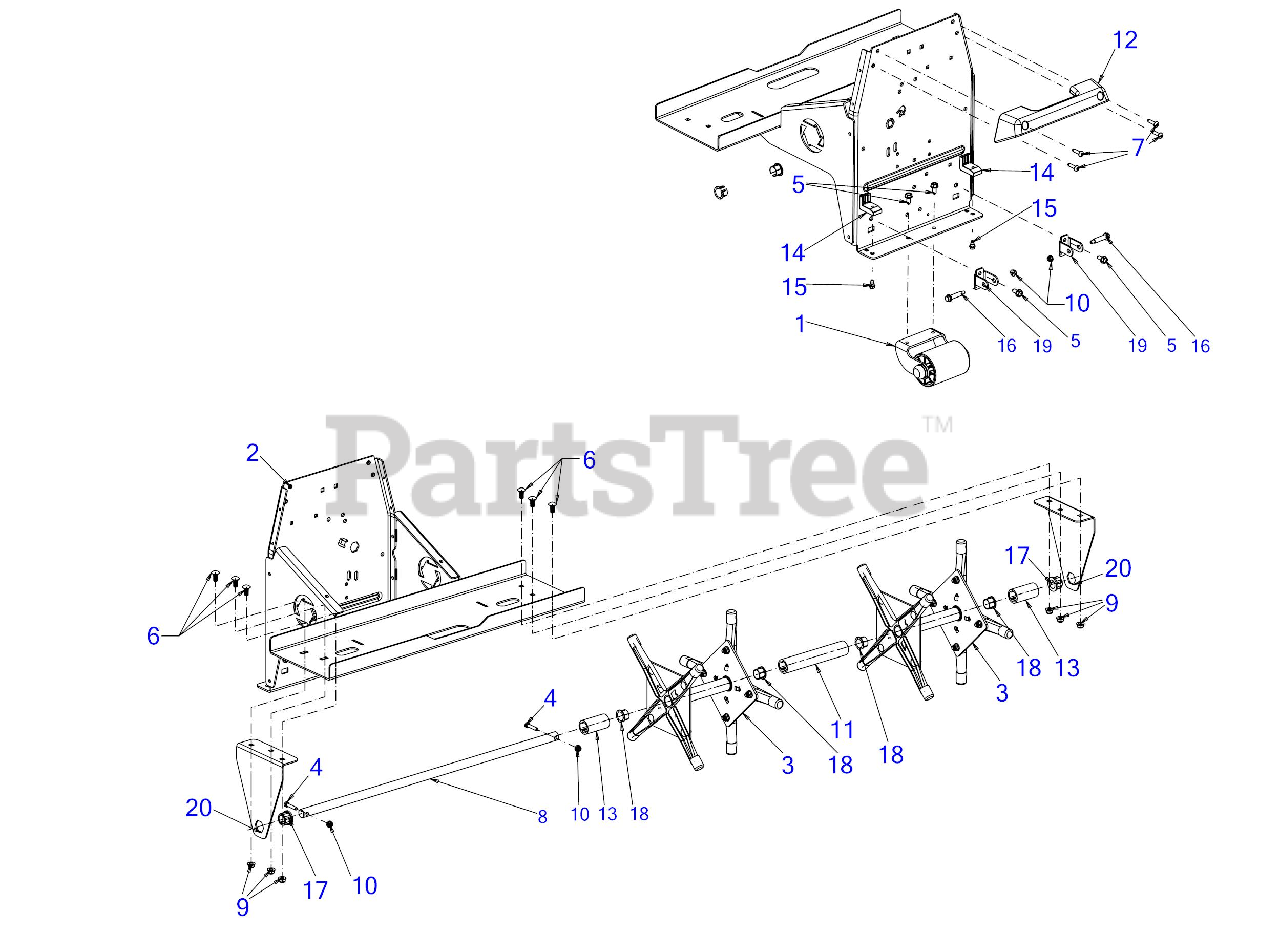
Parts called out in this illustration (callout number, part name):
1	ROLLER BRACKET ASSEMBLY
2	AERATOR FRAME ASSEMBLY
3	AERATOR DOUBLE WELD ASSEMBLY
4	HEX SCREW 1/4-20 x 1.25
5	SCREW 5/16-18 x .750
6	CARRIAGE BOLT 5/16-18 x .75
7	SCREW 1/4-20 x 1.0
8	CORE AERATOR AXLE
9	FLANGE LOCK NUT 5/16-18
10	FLANGE LOCK NUT
13	SPACER - .75 x 1.25 x 2.4
14	BUMPER PAD
15	SHOULDER SCREW 1/4-20 x .50
16	SHOULDER SCREW
17	FLANGE BEARING
18	FLANGE BUSHING
19	SUPPORT BRACKET
20	AXLE SUPPORT BRACKET
